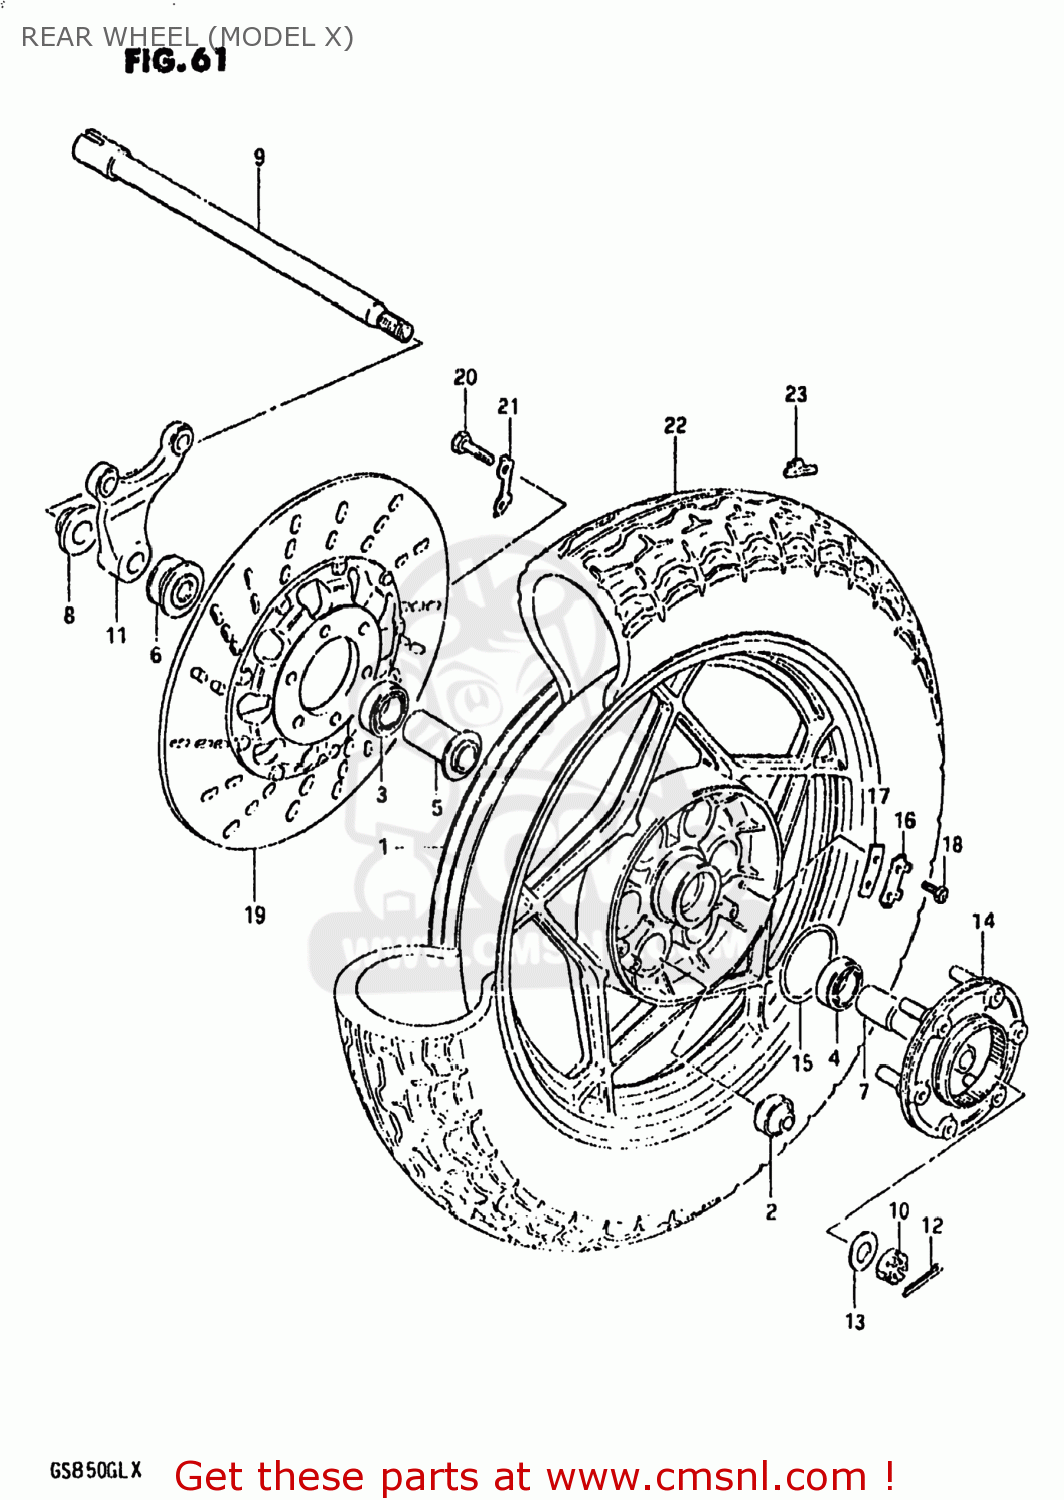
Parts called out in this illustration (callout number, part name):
1	WHEEL SET,REAR
2	BUSH
3	BEARING
4	BEARING
5	SPACER,REAR HUB BEARING
6	SPACER,REAR AXLE
7	SPACER,REAR AXLE,LEFT
8	SPACER,REAR AXLE,RIGHT
9	AXLE,REAR
10	NUT
11	BRACKET,RR,CALIPER
12	PIN,COTTER
13	WASHER (17.5X36X3.2)
14	JOINT ASSEMBLY,REAR HUB DRUM
15	O RING(D:2.1,ID:65)
16	JOINT WASHER
17	WASHER,THRUST(T:1.6)
18	SCREW
19	DISC,RR BRAKE
20	BOLT(8X25)
21	WASHER
22	TIRE
23	BALANCER,WHEEL
